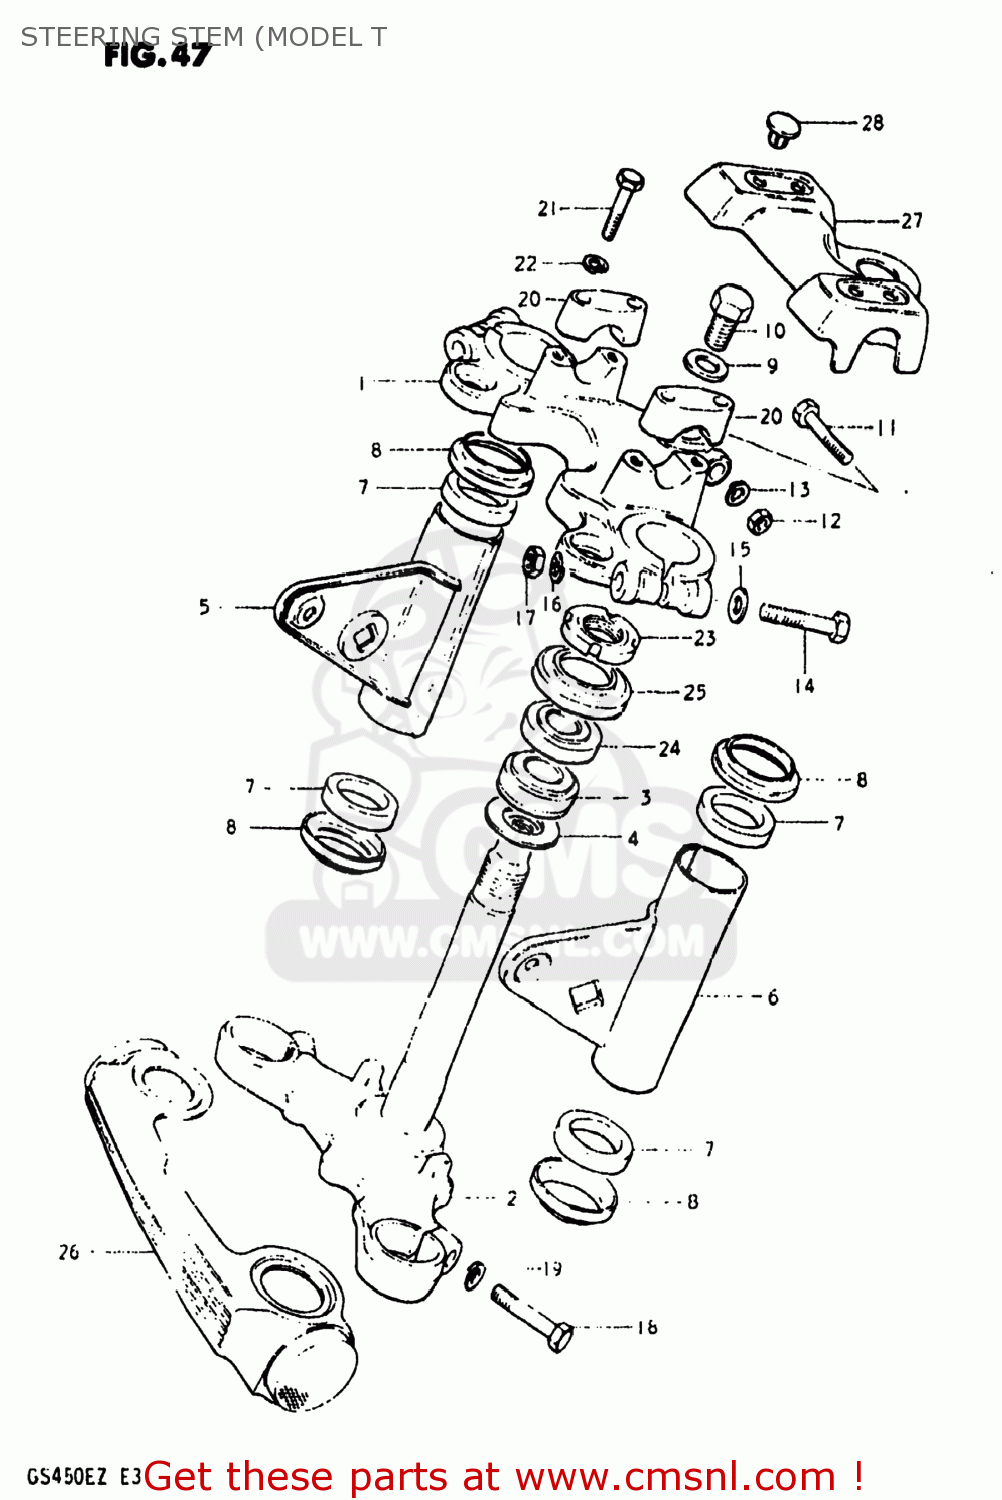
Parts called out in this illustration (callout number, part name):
1	HEAD,STEERING STEM
2	STEM,STEERING
3	BEARING
4	WASHER,THRUST
5	BRACKET,HEADLAMP,RIGHT
6	BRACKET,HEADLAMP,LEFT
7	CUSHION,HEADLAMP BRACKET
8	CAP,HEADLAMP BRACKET
9	WASHER
10	BOLT(12X20)
11	BOLT
12	NUT
13	LOCK WASHER
14	BOLT 10X55
15	WASHER
16	LOCK WASHER
17	NUT
18	BOLT 10X40
19	LOCK WASHER
20	HOLDER,HANDLE UPR
21	BOLT 8X35
22	WASHER,LOCK,8.
23	NUT,STEERING STEM(25X44X10)
24	TAPER,ROLLER BEARING
25	DUST SEAL,STEERING,UPPER
26	COVER,FR FORK
27	PAD,HANDLE
28	CAP(OD:19.5)
